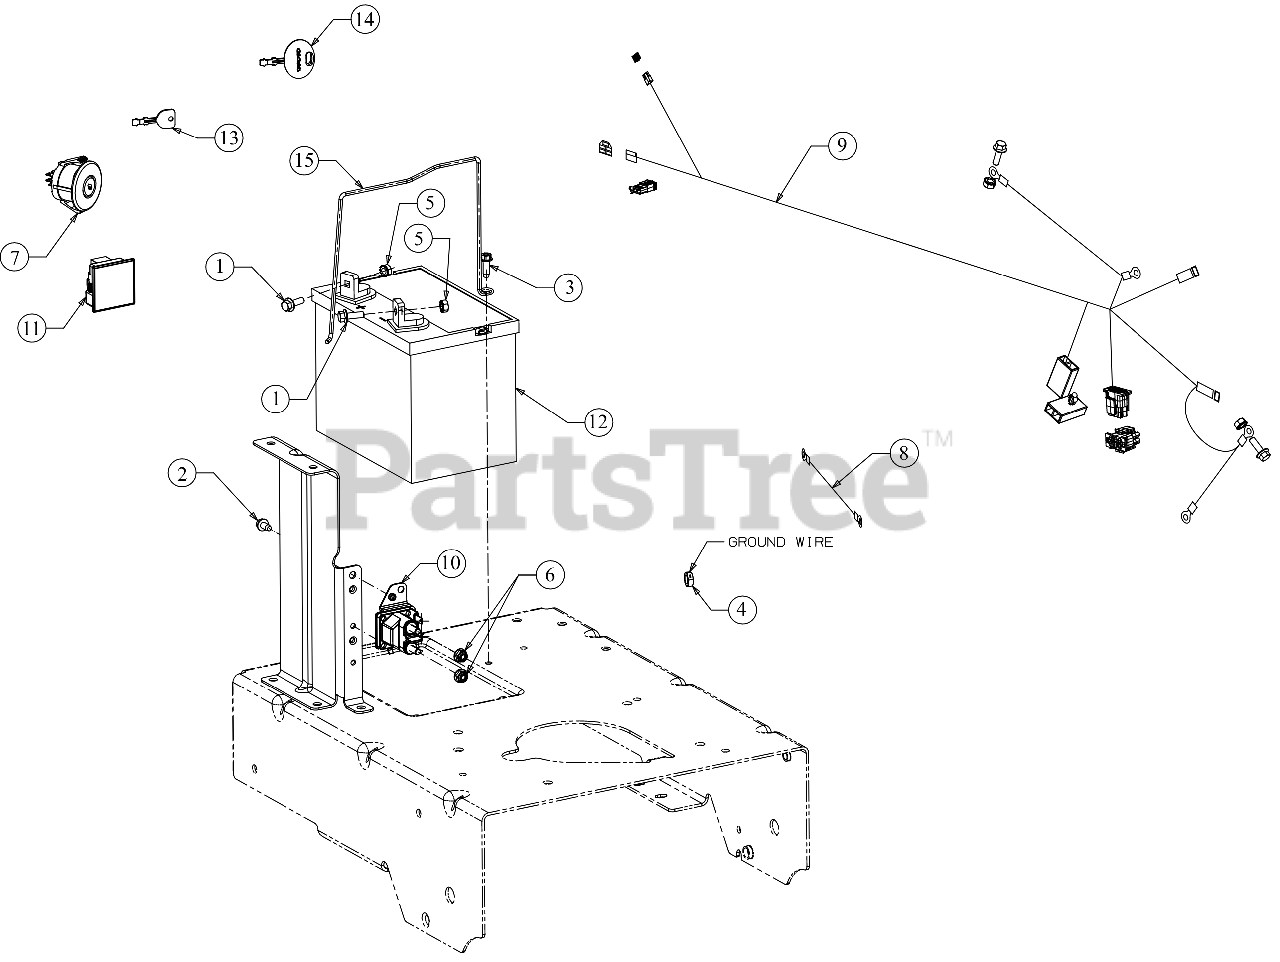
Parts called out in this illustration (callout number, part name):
1	SCREW 1/4-20 X .75 GR5
2	SCREW 1/4-20 X.500
3	SCREW 1/4-20 X .750
4	JAM LOCK NUT
5	SEMS NUT 1/4-20
6	FLANGE LOCK NUT
7	KEY SWITCH 3 POSITION
8	STARTER HARNESS
9	HARNESS
10	SOLENOID-12V 100A
11	HOUR METER
12	BATTERY
13	IGNITION KEY
14	IGNITION KEY
15	BATTERY HOLD DOWN STRAP
